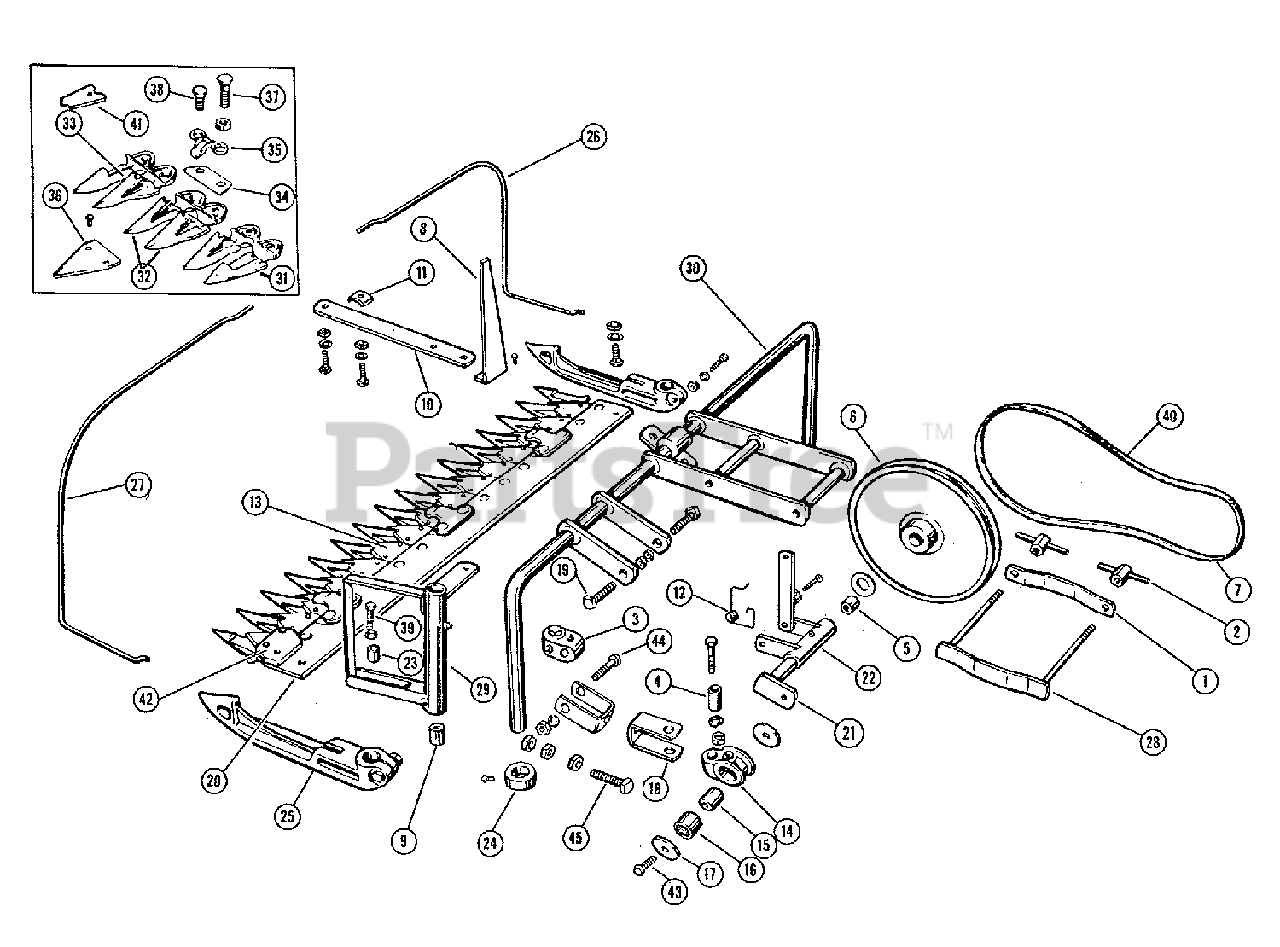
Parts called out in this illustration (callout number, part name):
1	SIDE PLATE, Hitch
2	T-NUT, Complete
3	PIVOT BLOCK
4	BEARING, Pivot Block
5	BUSHING, Bearing Bracket
7	BELT, 33", 2 H.P. only
9	BUSHING, Sickle Crank
10	BRACKET, Grass Finger
11	CLAMP, Grass Finger
12	SPRING, Belt Release
13	SICKLE, Complete w/ Head
14	BEARING HOUSING, Pitman
15	BEARING, Inner Race, Pitman
16	BEARING, Needle, Pitman
17	BEARING, Washer, Pitman
18	CLEVES, Pitman
19	CAP SCREW, Special
20	CUTTER BAR, Slab, 30"
21	CRANKSHAFT ASSEMBLY
22	BRACKET ASSEMBLY, Bearing, w/ Bushings
23	BUSHING, Sickle Head
24	COLLAR, Set
25	SHOE, Sickle Bar
26	GRASS FINGER, Right
27	GRASS FINGER, Left
28	CLAMP, Hitch
29	SICKLE BELL CRANK, w/ Bearing, Bushing, & Sickle Head Bolt
30	FRAME, Sickle Bar
31	GUARD, Left End
32	GUARD, Twin
33	GUARD, Right End
34	PLATE, Wear
35	CLIP, Sickle
36	SICKLE SECTIONS
37	GUARD BOLT, Long
38	GUARD BOLT, Short
40	BELT, 37", 3 HP Only
41	PLATES, Ledger
42	SICKLE, Head Only
